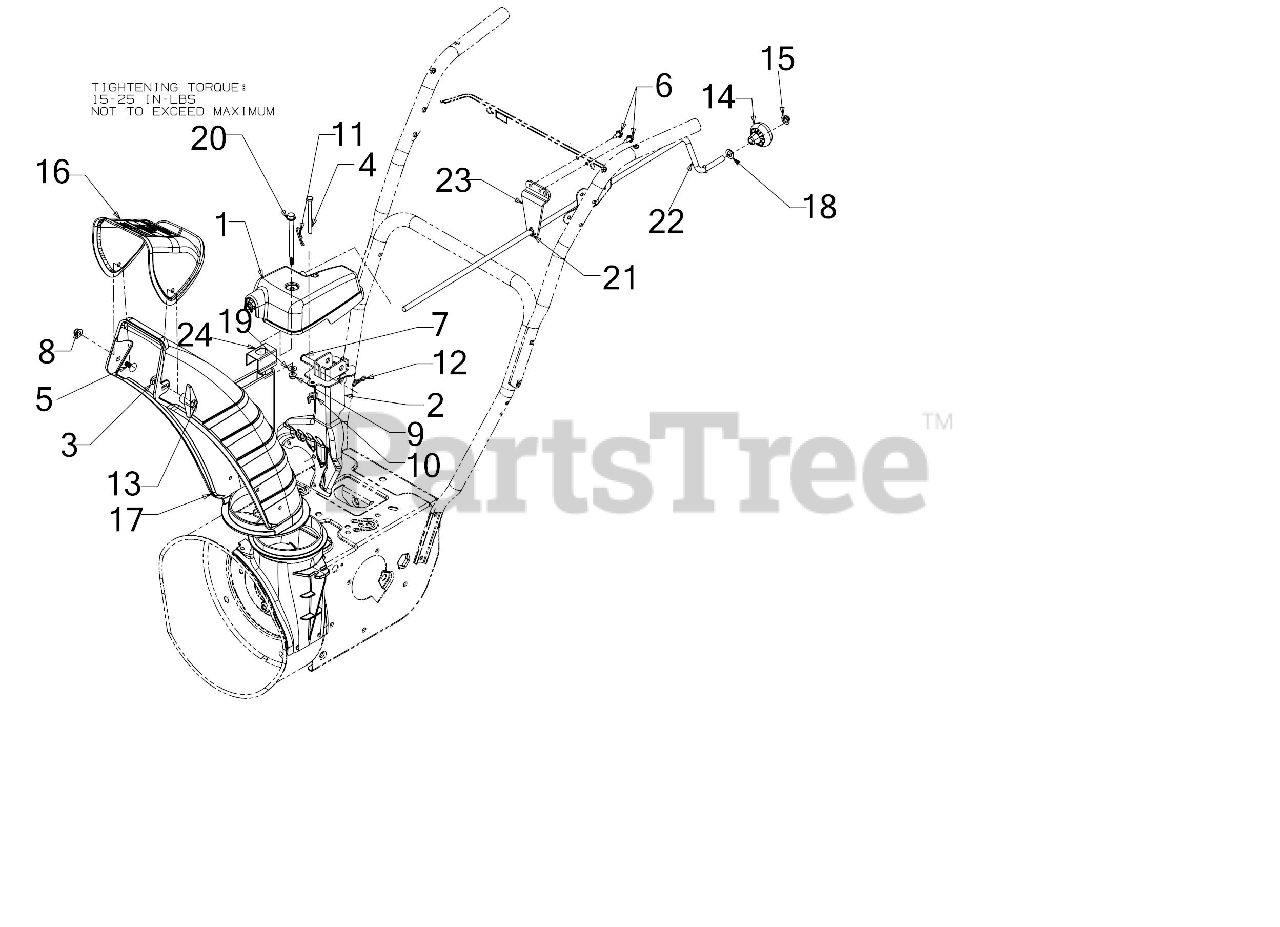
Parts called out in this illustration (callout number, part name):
1	WORM GEARBOX ASSEMBLY
2	CHUTE SUPPORT BRACKET ASSEMBLY
3	CARRIAGE BOLT 5/16-18 x 1
4	SCREW 1/4-20 x 3.0 GR5
5	CARRIAGE BOLT 5/16-18 x .75
6	SCREW 1/4-20X.625
7	CLEVIS PIN 3/8 x 1.87
8	FLANGE LOCK NUT 5/16-18
9	FLANGE LOCK NUT
10	WING NUT 1/4-20
11	INTERNAL COTTER PIN
12	BOW TIE COTTER PIN 1/4-5/16
13	WING NUT KNOB
14	SHIFT KNOB
15	PUSH NUT
16	UPPER CHUTE
17	LOWER CHUTE 5" DIA
18	FLAT WASHER
19	FLAT WASHER
20	SHOULDER SCREW
21	BUSHING .380 ID
22	CHUTE CRANK
23	ROD SUPPORT BRACKET
24	CHUTE BRACKET
